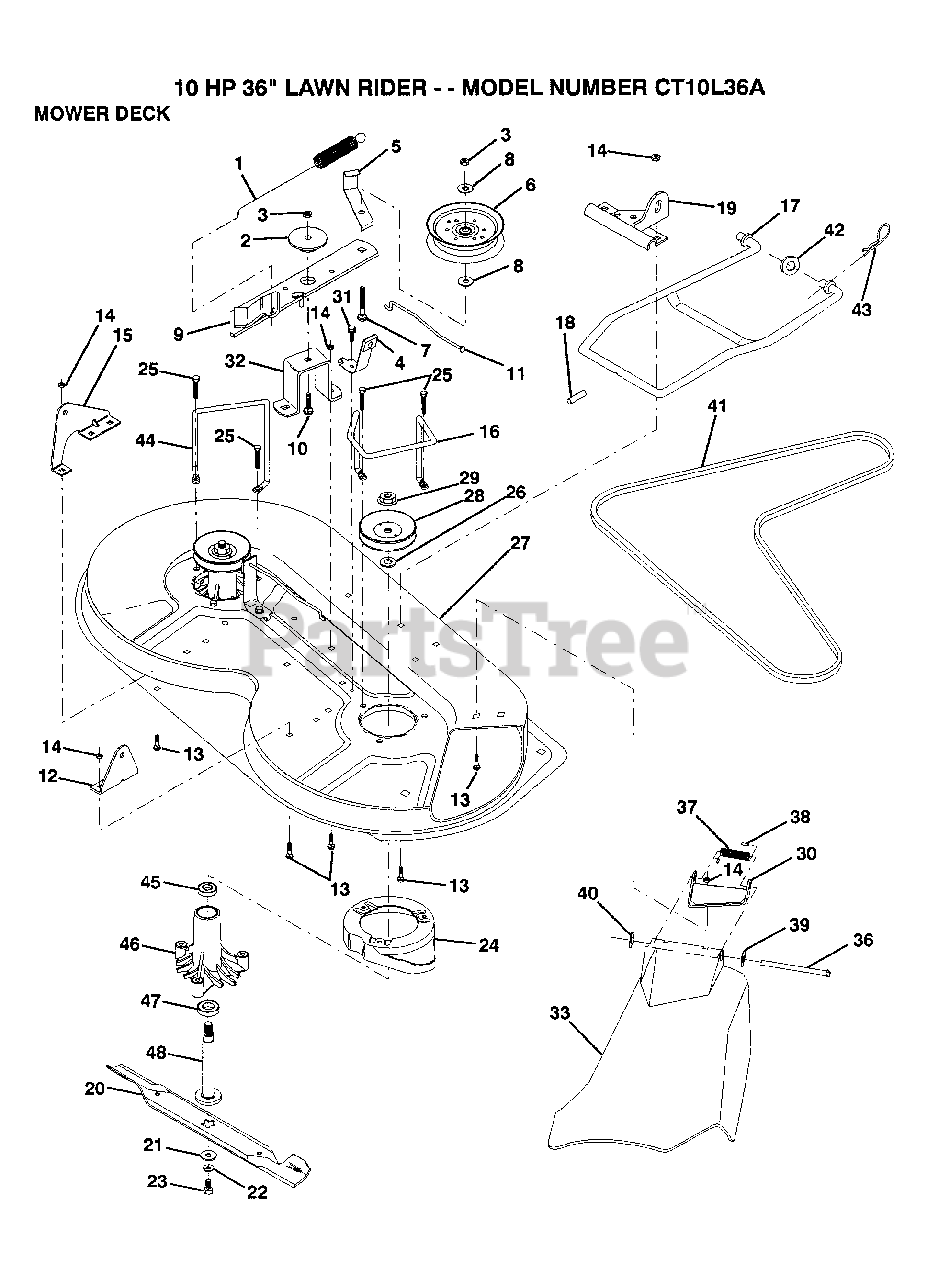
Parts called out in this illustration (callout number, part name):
2	SPACER RETAINER
4	BRAKE ASM
5	IDLER BELT GUIDE
6	PULLEY IDLER
7	BOLT
8	WASHER
10	BOLT D
11	BRAKE ROD
12	"BRKT,LIFT REAR"
13	BOLT
15	"BRKT,LIFT REAR LH"
17	MOWER LINK STAB
18	"PIN,GROOVE"
19	"BRKT,LINK STABILI"
20	"BRKT,LINK STABILI"
21	WASHER BLADE
23	BLADE BOLT
26	WASHER
31	SCREW LT
32	"SUPT,IDLER ARM"
36	HINGE ROD
37	SPRING TORSION
38	CAP-SLEEVE LT
39	WASHER
40	NUT PUSH M
41	V-BELT.PRIM.78.5.
43	RETAINER.SPRING
45	BEARING
46	HSG ASM MANDREL
47	BEARING.BALL
